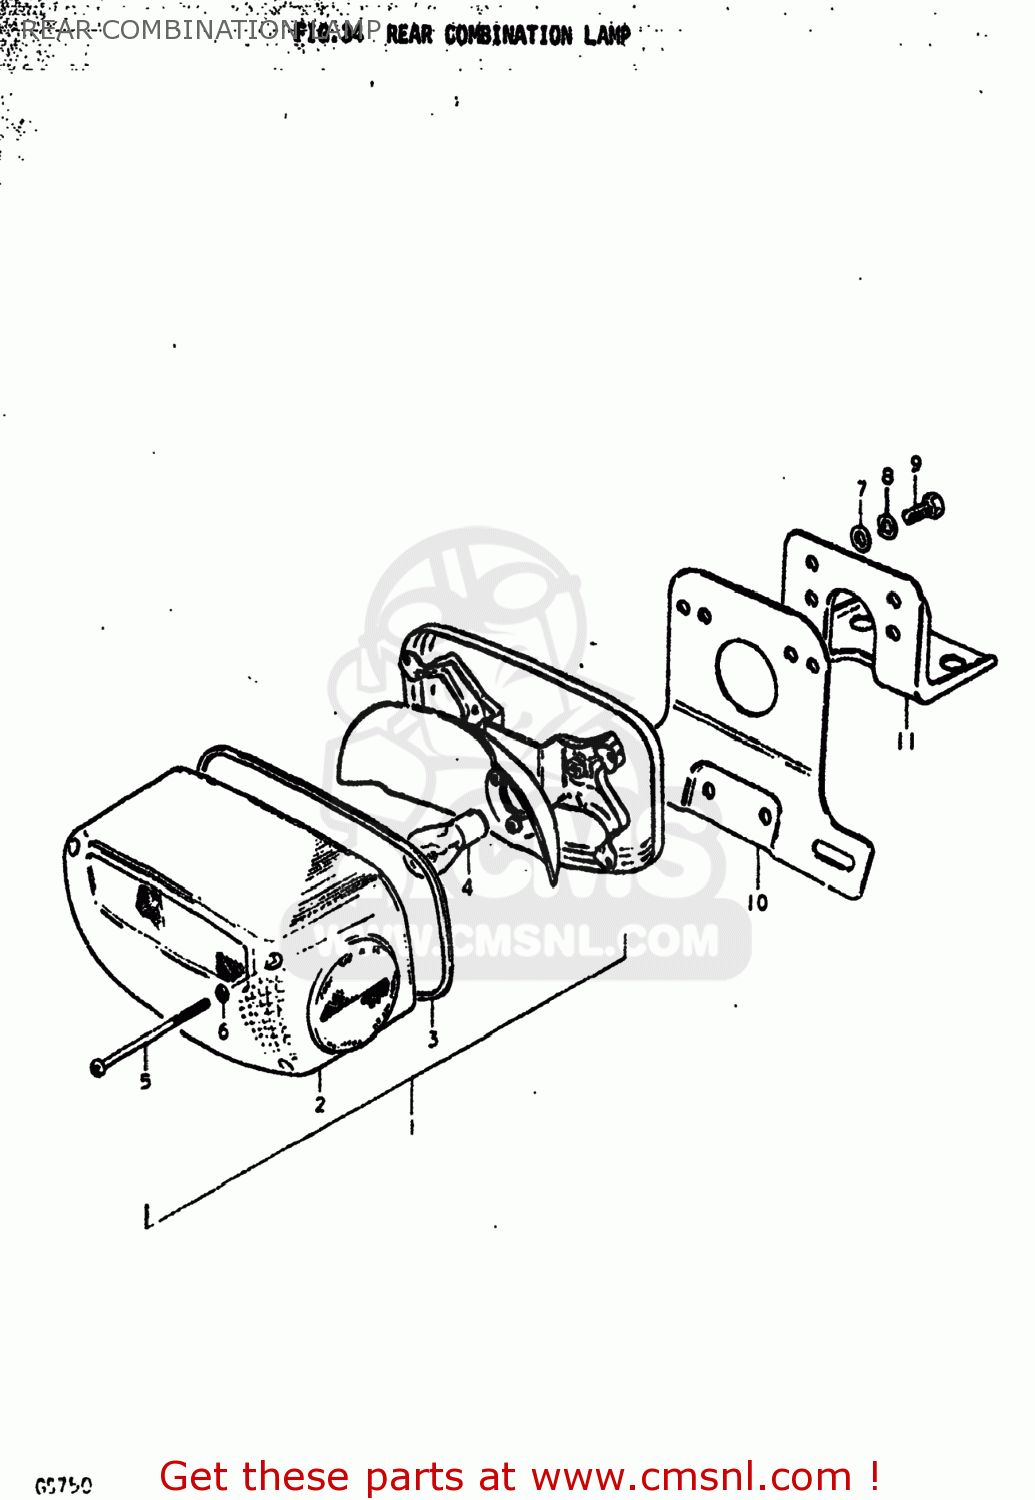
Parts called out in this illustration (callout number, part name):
1	LAMP ASSEMBLY,REAR COMBINATION
2	LENS,REAR COMBINATION LAMP
3	GASKET (NAS)
4	BULB(12V23W)
5	SCREW
6	GASKET (NAS)
7	WASHER
8	LOCK WASHER
9	BOLT
10	BRACKET,LICENSE PLATE
11	BRACKET,LICENSE PLATE
